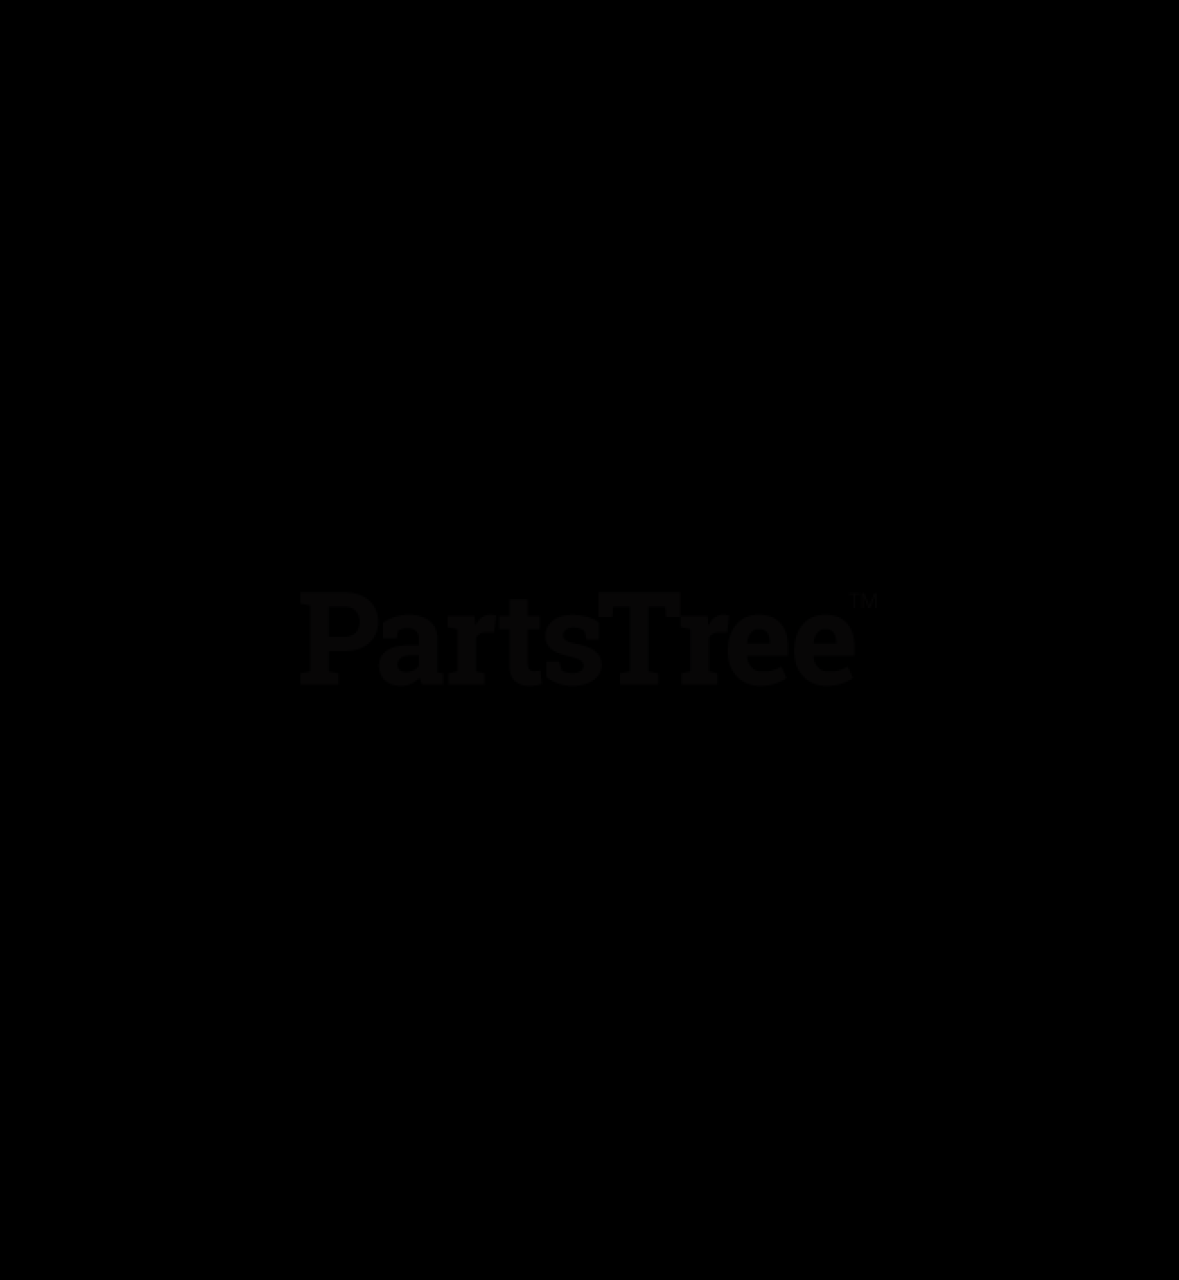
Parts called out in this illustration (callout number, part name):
1	60-in. Discharge Baffle (215)
2	Nut, .31-18 Nyloc Flange
3	Bolt, Round Head Square Neck .31-18 x 1.00 Grade 5
4	Nut, Heavy Hex .38-16
5	60-in. Right Hand Spindle Guard (215)
6	60-in. Left Hand Spindle Guard (215)
7	Nut, Spin Lock-Flange .375-16
8	Nut .50-13 Nyloc Flange
9	Anti-Scalp Wheel
11	Bolt-Round Head Square Neck .50-13 x 5.00
12	60-in. Mower Deck (215)
13	Knob, Clamping, .312-18 Nyloc
14	Pin, Pull Plunger .50-13 Thread x .310
15	Nut, Locking Center .31-18
16	Spacer, .510 x .625 x 3.35
17	Chute, Storage Bracket
18	Bolt, Hex .38-16 x 1.00 Grade 5
19	Nut, .38-16 Nyloc Flange
20	Bolt, Round Head Square Neck .50-13 x 8.50
21	Bolt, Round Head Square Neck .31-18 x 1.50
22	Bumper, Recessed 1.50 x .63 , .31 Thru Hole
23	60-inch Discharge Chute Mounting Weldment (215)
24	Rubber Discharge Chute Support
25	Bolt, Round Head Square Neck .38-16 x 1.00 Grade 5
26	Chute, Rubber Discharge
27	Bolt, Round Head Square Neck .38-16 x 1.25 Grade 5
28	Bolt, Hex .38-16 x 1.25 Grade 5
